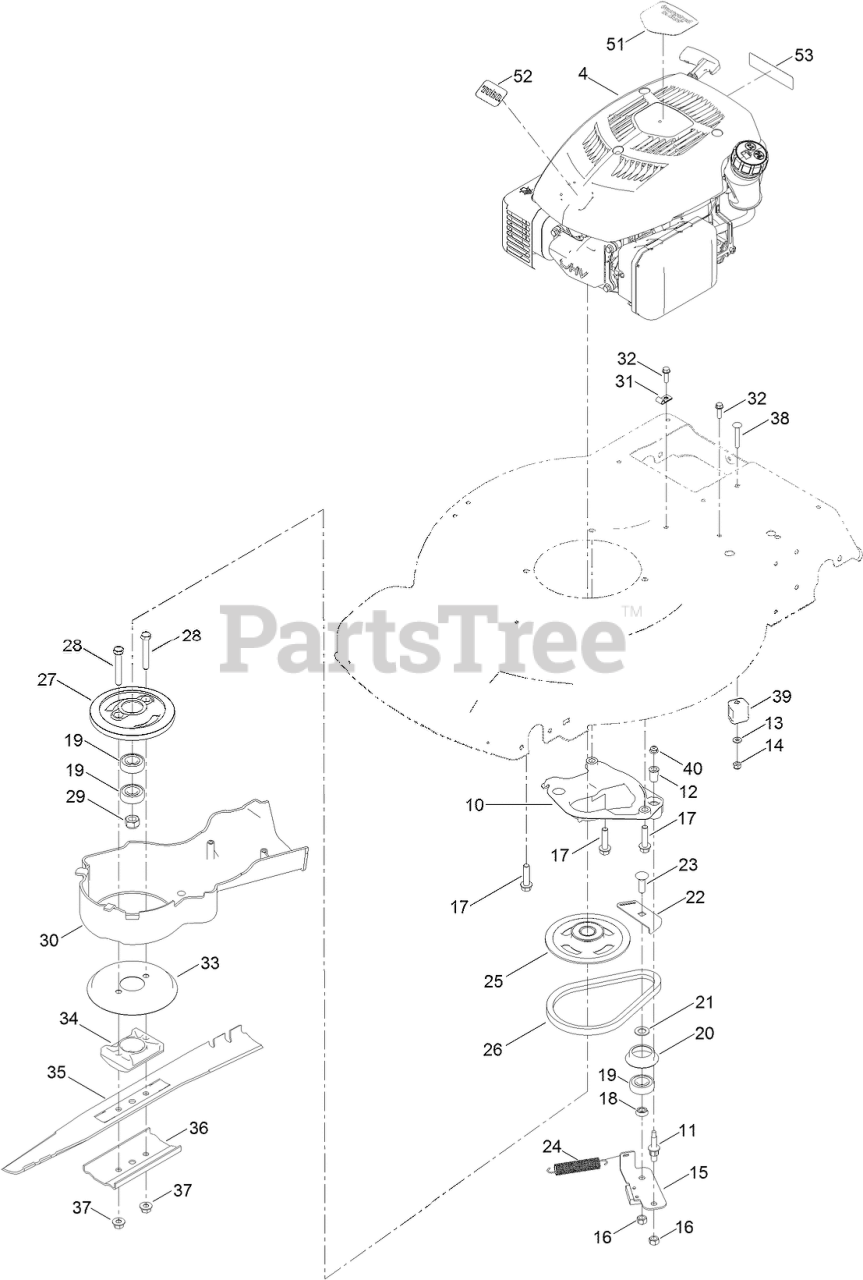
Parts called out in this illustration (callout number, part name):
4	ENGINE-1P65F-2
10	PLATE-ANCHOR
11	BOLT-SHOULDER
12	BUSHING
13	WASHER-FLAT
14	NUT-LOCK, NI
15	PLATE-BRAKE
16	LOCKNUT
17	SCREW-HWH
18	SPACER-BEARING
19	BEARING-BALL
20	RETAINER-BELT
21	SPACER
22	PLATE-GUIDE
23	SCREW-CARR
24	SPRING-TENSION, BRAKE
25	PULLEY
26	BELT
28	SCREW-HH
29	NUT-HEX
31	CLIP-CLOSED, INSULATED
32	SCREW-HWH
33	DISC
34	SUPPORT-BLADE
35	BLADE-22 INCH
36	SUPPORT-BLADE
37	NUT-FLANGE, LOCK
38	SCREW-CARR
39	ANCHOR-CABLE
40	NUT-HF
51	DECAL-SHROUD
53	DECAL-ARRESTOR, SPARK
